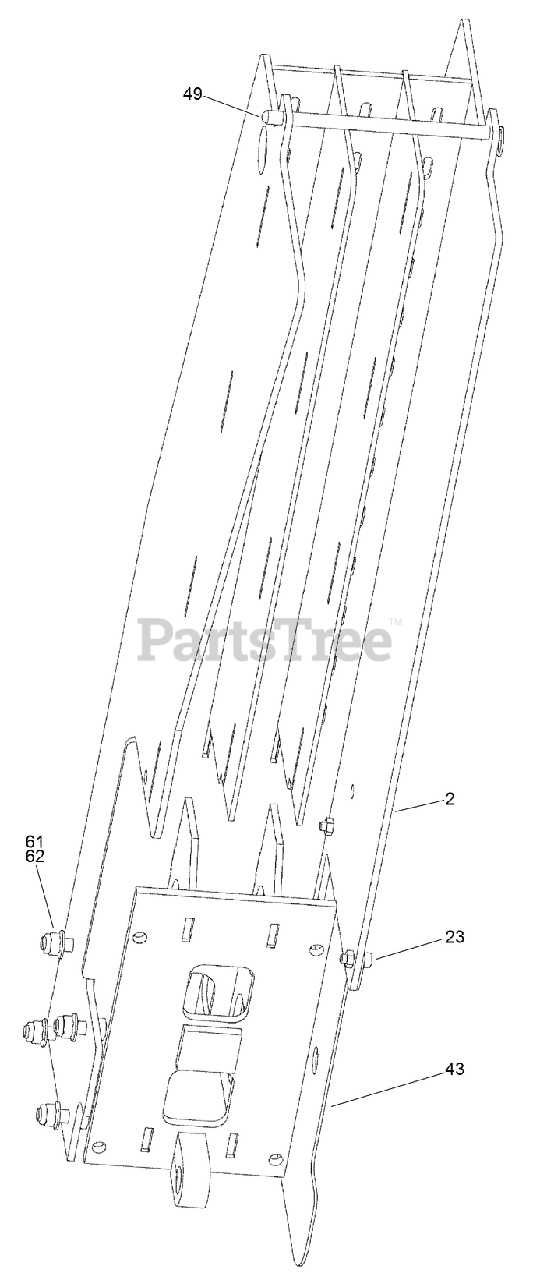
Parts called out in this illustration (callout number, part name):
2	WELDMENT - Rear Rod Box
23	SCREW, METRIC FLANGE w/BODY - M8 x 20
43	PLATE - Guard
61	NUT-HHF, LOCK
62	SCREW-HFH
